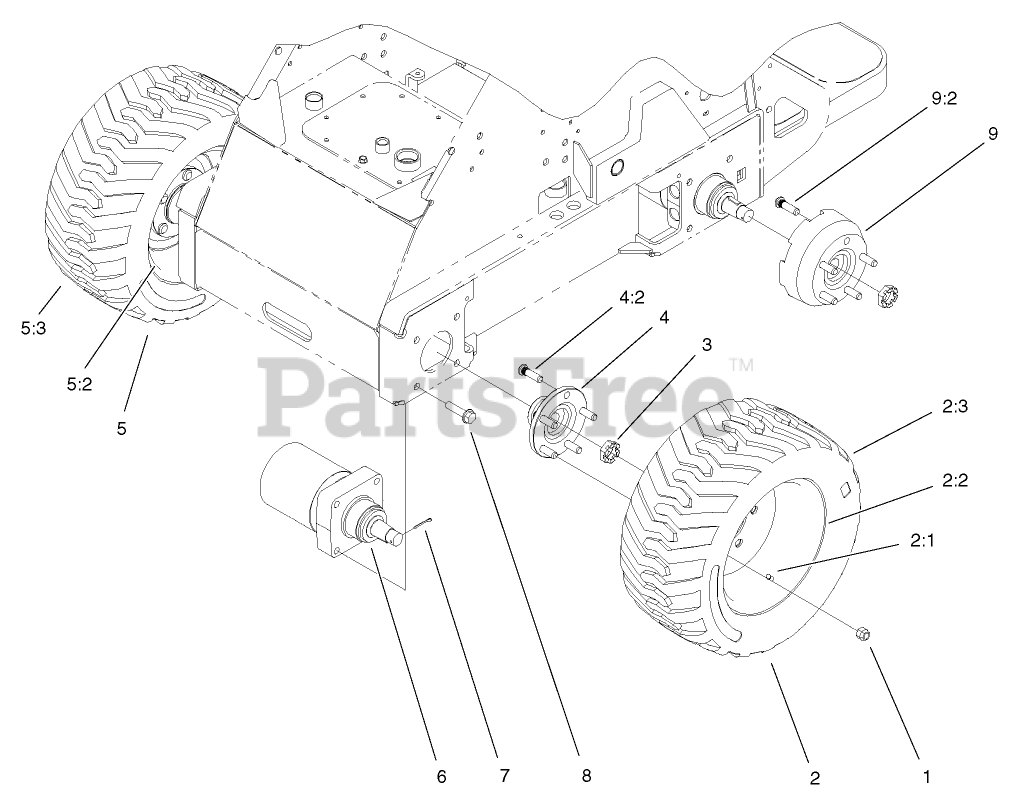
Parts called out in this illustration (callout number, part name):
1	NUT-LUG
2	LH WHEEL AND TIRE ASM
2:1	STEM-VALVE
2:2	WHEEL
4	HUB ASM
4:2	STUD-TYPE, DRIVE
5	RH WHEEL AND TIRE ASM
5:2	WHEEL
6	HYD MOTOR ASM
7	PIN-COTTER
8	SCREW-HHF
9	HUB ASM
9:2	STUD-TYPE, DRIVE
